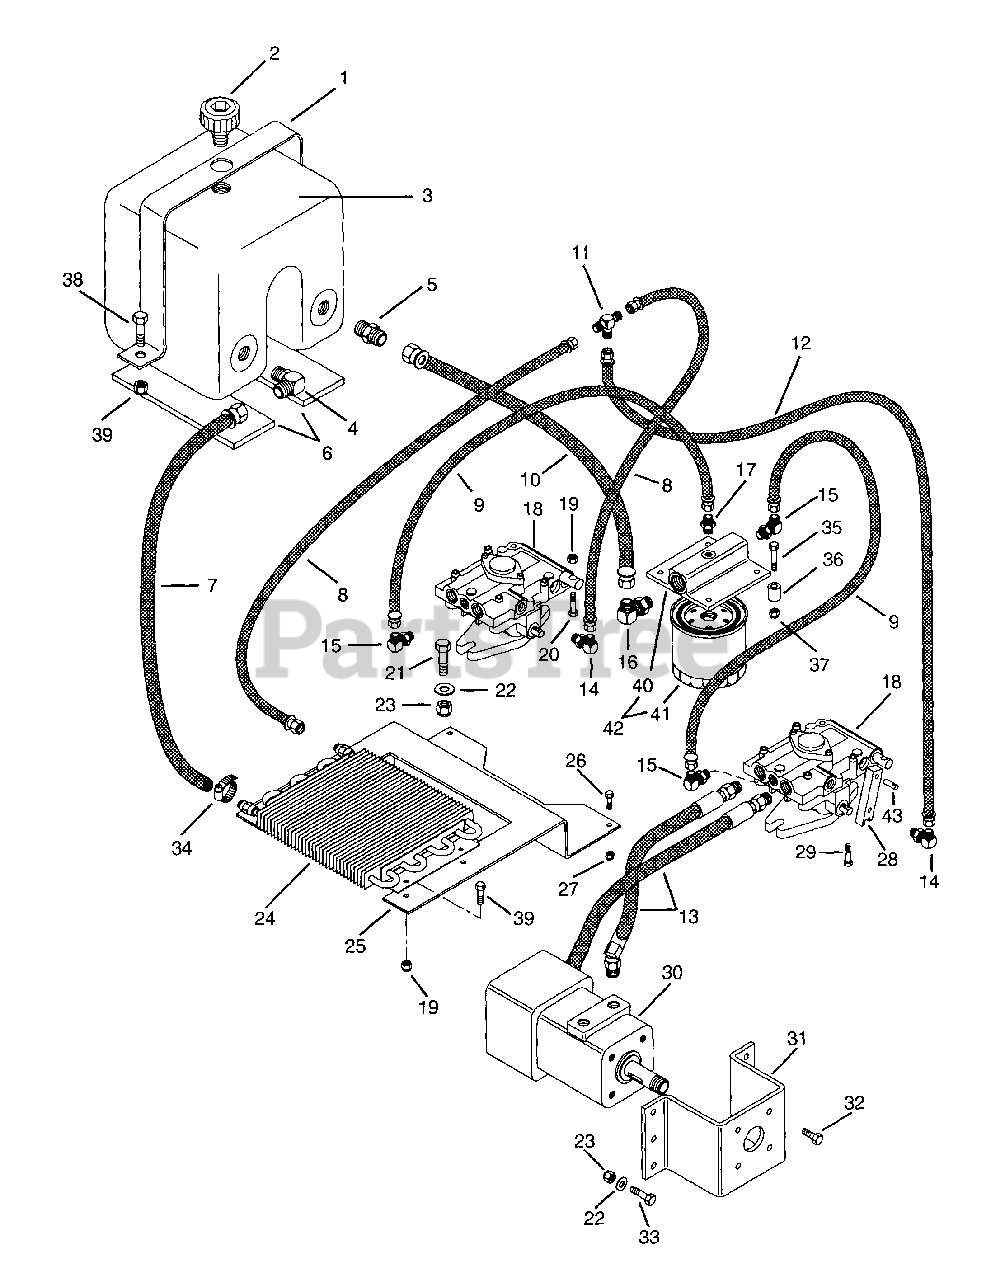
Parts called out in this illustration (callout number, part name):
1	Strap-Tank
2	Cap-Filter
3	Tank-Hydraulic
4	Adapter .37 - .875
5	Adapter-Hydraulic
6	Pad-Gas Tank
7	Hose-Hydraulic Cooler to Tank
8	Hose-Hydraulic Valve to Tank
9	Hose-Oil Filter to Pump
10	Hose-Hydraulic Tank to Filter
11	Adapter-Tee .56-18
12	Hose-Pump to Tee
13	Assembly-Hose Wheel Motor to Pump
14	Adapter 2503-6-6
15	Adapter 2503-4-4
16	Adapter-Pipe .75-16
17	Adapter 0503-4-4
18	Variable Displace Pump
18	Kit-Pump Seal
19	Nut-Locking-Center .25-20
20	Bolt-Hex .25-20 x 1.63
21	Bolt-Hex .38-16 x 1.125 Grade 5
22	Washer-Flat-Steel .406 x .812 x .065
23	Nut-Locking-Center .38-16
24	Cooler-Oil
25	Bracket-Oil Cooler
26	Bolt-Hex .38-16 x 1.125 Grade 5
27	Nut-Locking-Center .38-16 Grade 2
28	Arm-Pump Actuating
29	Bolt-Hex .25-20 x 1.25 Grade 5
30	Motor-Hydraulic Wheel
31	Bracket-Wheel Motor
32	Bolt-Hex .380-16 x .75 Grade 5
33	Bolt-Hex .38-16 x 1.00 Grade 5
34	Clamp .88 Diameter Hose
35	Bolt-Hex .31-18 x 1.75 Grade 5
36	Bushing-Split-Steel .328 x .462 x 1.00
37	Nut-Locking-Center .31-18 Grade 2
38	Bolt-Hex .31-18 x .75 Grade 5
39	Bolt-Hex .25-20 x .75 Grade 5
40	Assembly-Head
41	Element
42	Assembly-Spin-On Lube
43	Pin-Dowel .312 x 1.25
